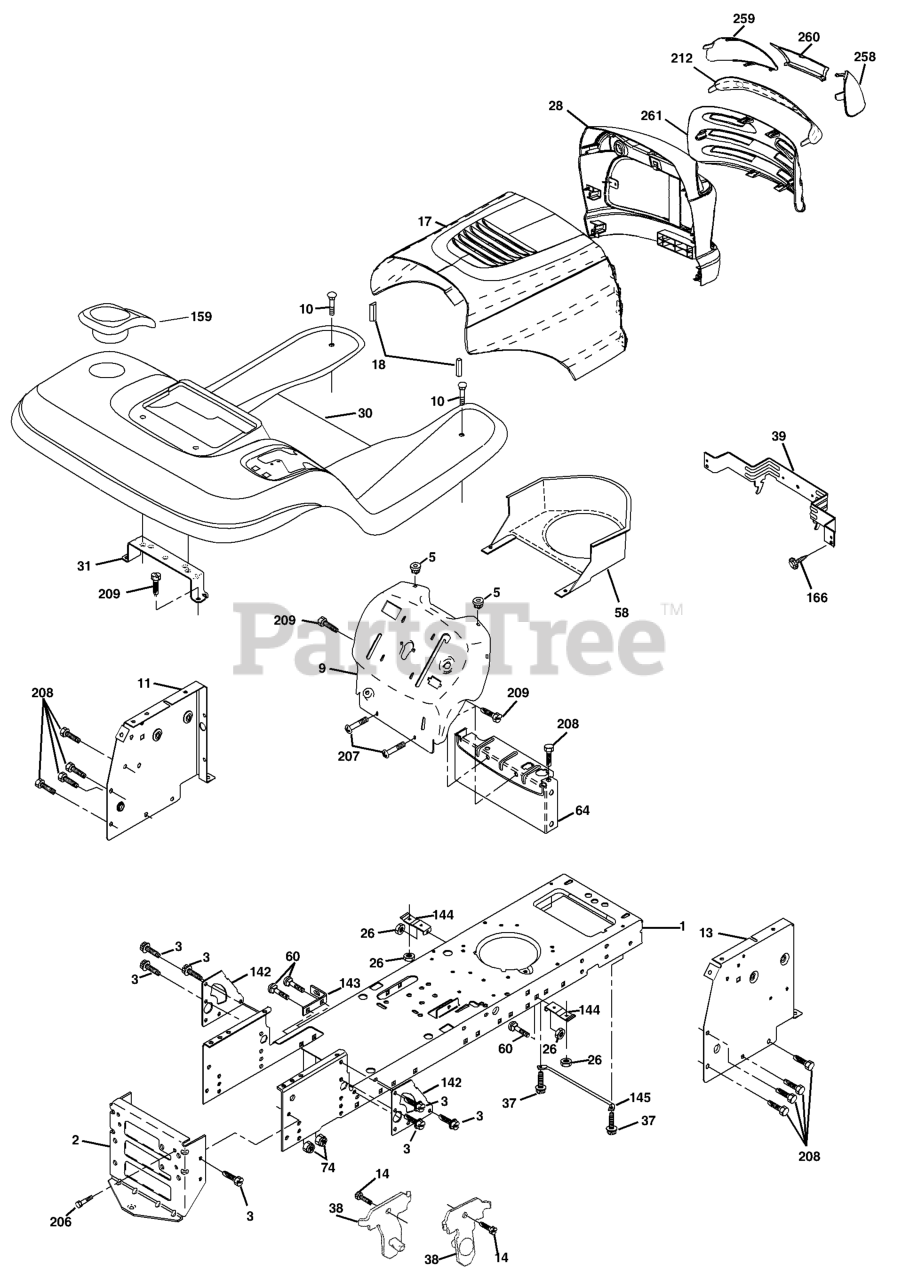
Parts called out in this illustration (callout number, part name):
1	CHASSIS STAMPING
2	DRAWBAR, 12GA
3	SCREW 3/8-16X3/4
5	BUMPER.RUBBER.HOOD
9	DASH
10	BOLT D
11	PANEL.DASH.LH.LTX
13	PANEL DASH RH
14	SCREW LT
17	HOOD
18	BUMPER.HOOD.LARGE.1.75"
26	NUT
28	GRILL/LEN.ASM.DL.HUSQ
30	FENDING
31	BRACKET.SUPPORT.FENDER
37	Screw Thdrol 6/16-18 x 1/2 TYT
38	BRACKET.ASM.PIVOT.MOWER.REAR
39	BRACKET PIVOT LASER
58	AIR DUCT P/L/LT
60	Bolt Rd Hd Sqnk 3/8-16 Unc x 3/4
64	DASH LOWER
142	PLATE REINFORCEMENT
143	BRACKET, SWAY BAR
144	BRKT, FOOT REST
145	ROD PIVOT CHASSIS/HOOD
159	CUPHOLDER
166	SCREW
206	SHOULDER BOLT 5/16-18TT
207	SCREW, 5/16-18 X 1/2
208	SCREW 3/8-16X1/2
209	SCREW, 3/8-16X3/4
212	INSERT.LENS.REFLECTIVE
258	LENS LH
259	LENS LH
260	COVER.LENS.HUSQ.( HAVE GRAY)
261	INSERT GRILLE
